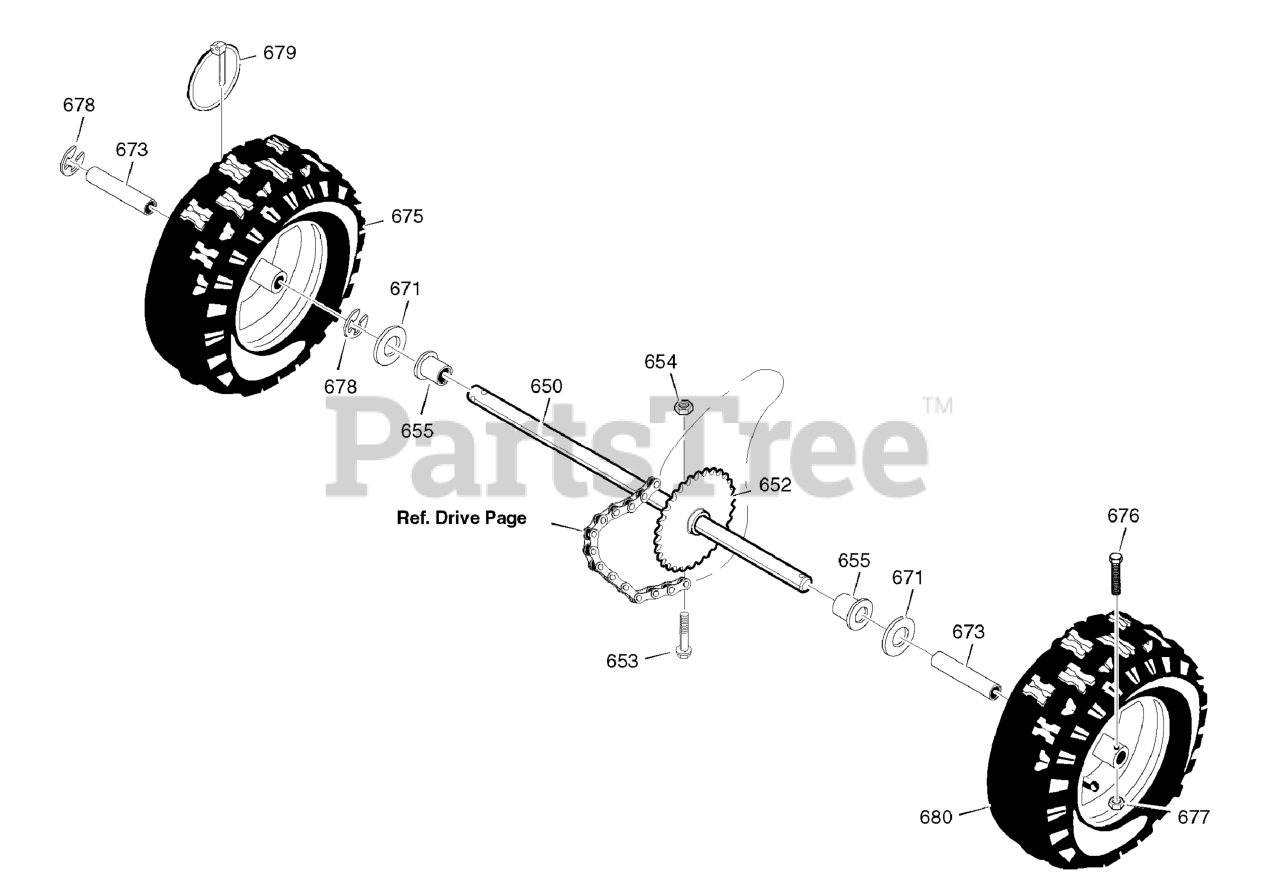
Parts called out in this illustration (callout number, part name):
650	SHAFT, AXLE
652	SPRKT & HUB
653	SCREW, 1/4-20 X 1.75
654	NUT, 1/4- 20 HEX NYLOCK
655	BEARING, AXLE
671	WASHER, FLAT
673	BUSHING, WHEEL
675	TIRE & RIM, RIGHT
676	SCREW, 1/4-20 X 1.75 HH
677	NUT, 1/4- 20 HEX NYLOCK
678	RING, RET
679	PIN, KLIK .25 X 1.38 DIA
680	TIRE & RIM, LEFT
